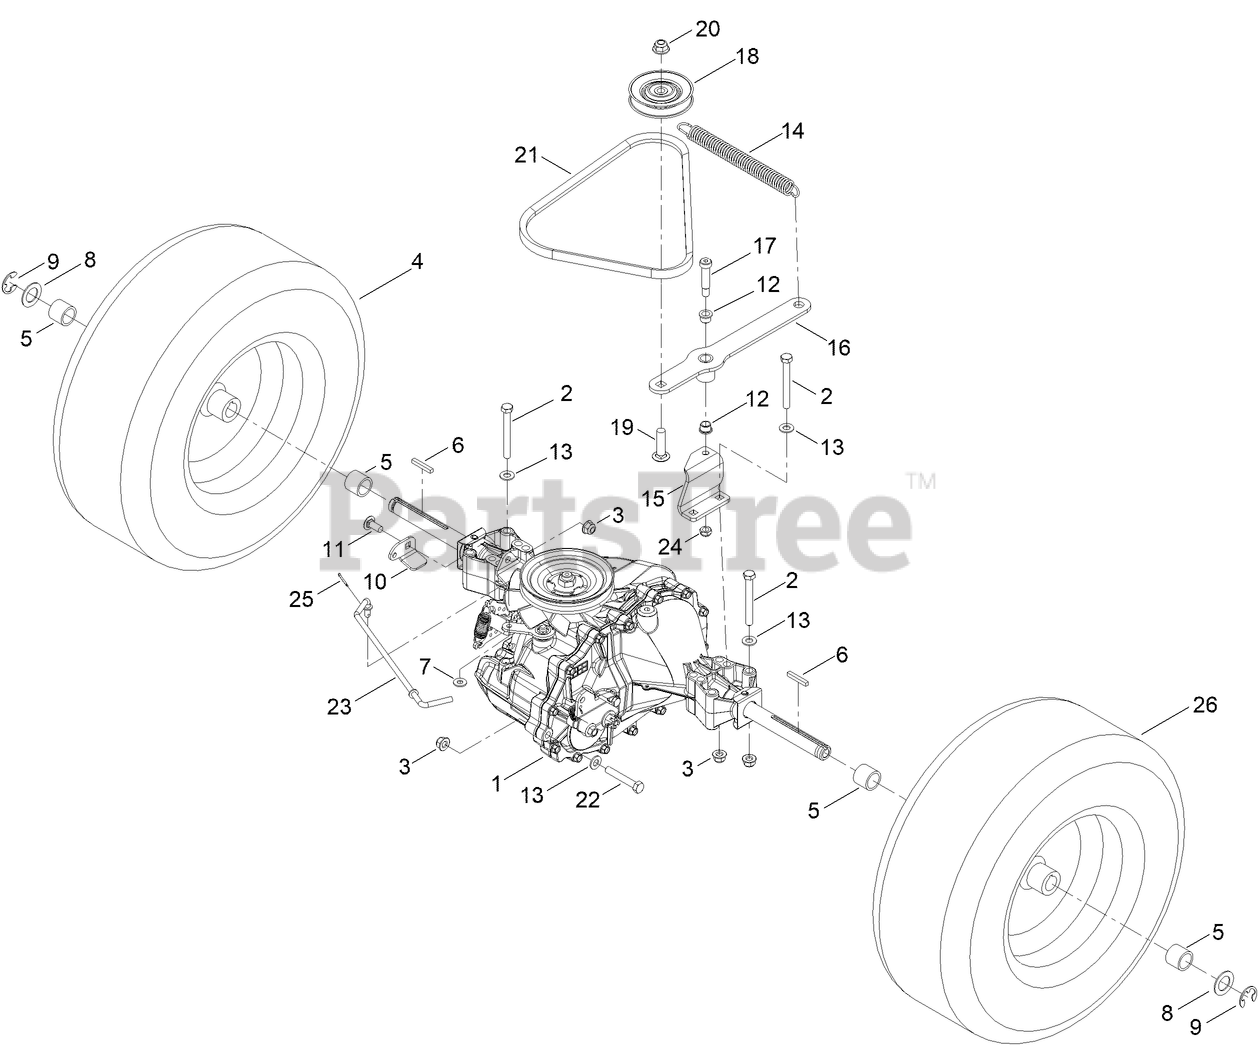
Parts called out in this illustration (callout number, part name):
1	TRANSAXLE ASM
2	SCREW-HH
3	NUT-HF, NI
4	TIRE ASM
5	SPACER
6	KEY-SQUARE
7	WASHER-FLAT
8	WASHER
9	E-RING
10	BRACKET-CABLE
11	SCREW-CARR
12	BUSHING
13	WASHER-PLAIN
14	SPRING-EXTENSION
15	MOUNT-ARM, TENSION
16	ARM-TENSION, BELT
17	SCREW-HSH
18	PULLEY
19	SCREW-CARR
20	NUT-HF, NI
21	V-BELT
22	SCREW-HH
23	LEVER-VALVE, TOW
24	NUT-LOCK, NI
25	PIN-COTTER
26	TIRE ASM, LEFT HAND
